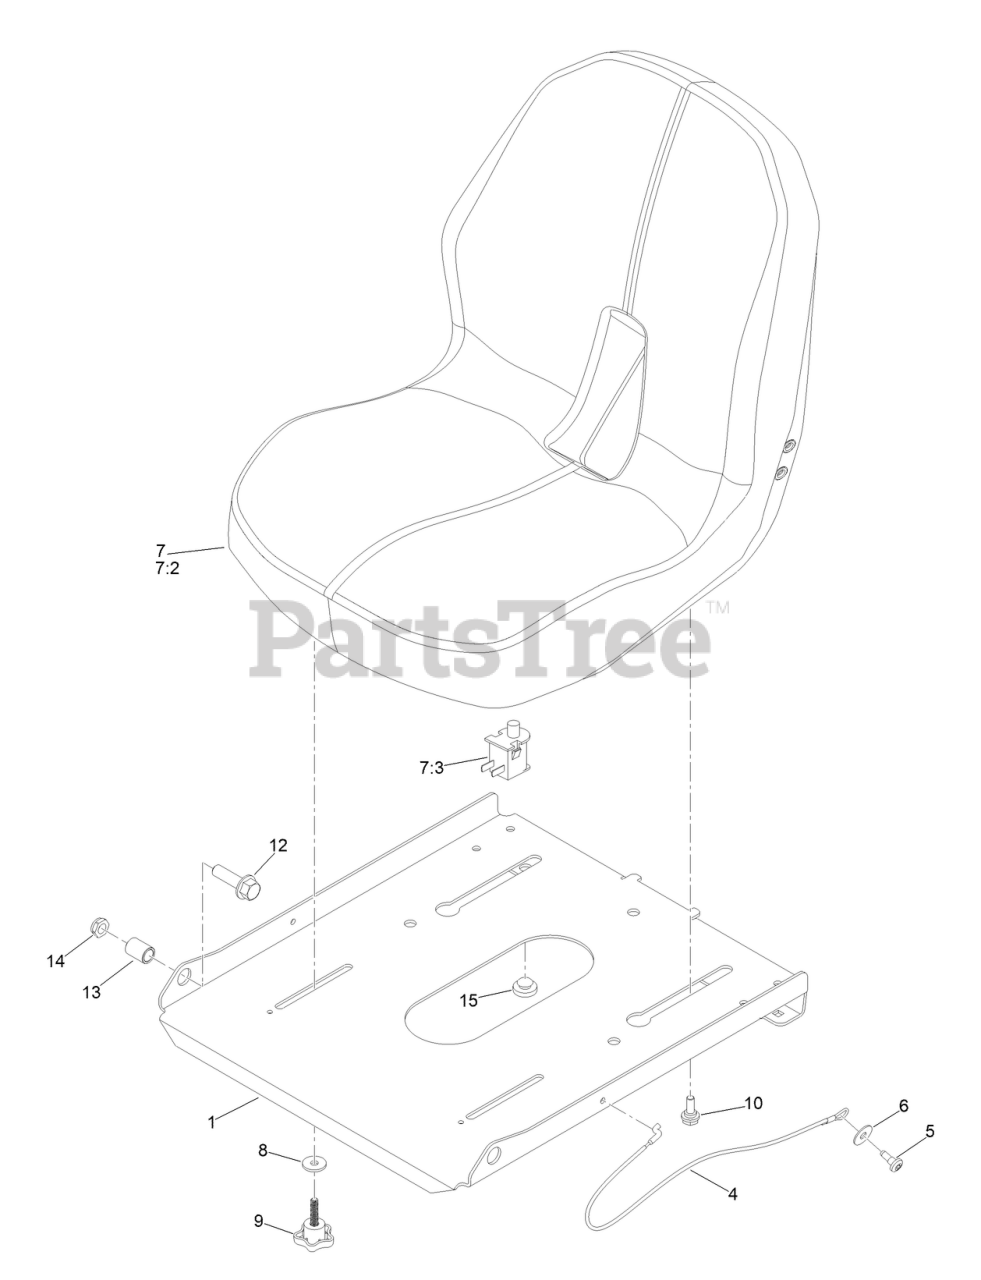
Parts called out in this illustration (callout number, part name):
1	PAN-SEAT, LOWERED
4	CABLE-LANYARD
5	SCREW-SHOULDER
6	WASHER-FLAT
7	SERVICE-SEAT
7:2	COVER-SEAT
7:3	SWITCH-BAIL
8	WASHER-FRICTION
10	BOLT-SHOULDER,HFH
12	SCREW-HHF
13	BUSHING-PIVOT, SEAT
14	NUT-HEX
15	BUMPER-SEAT
